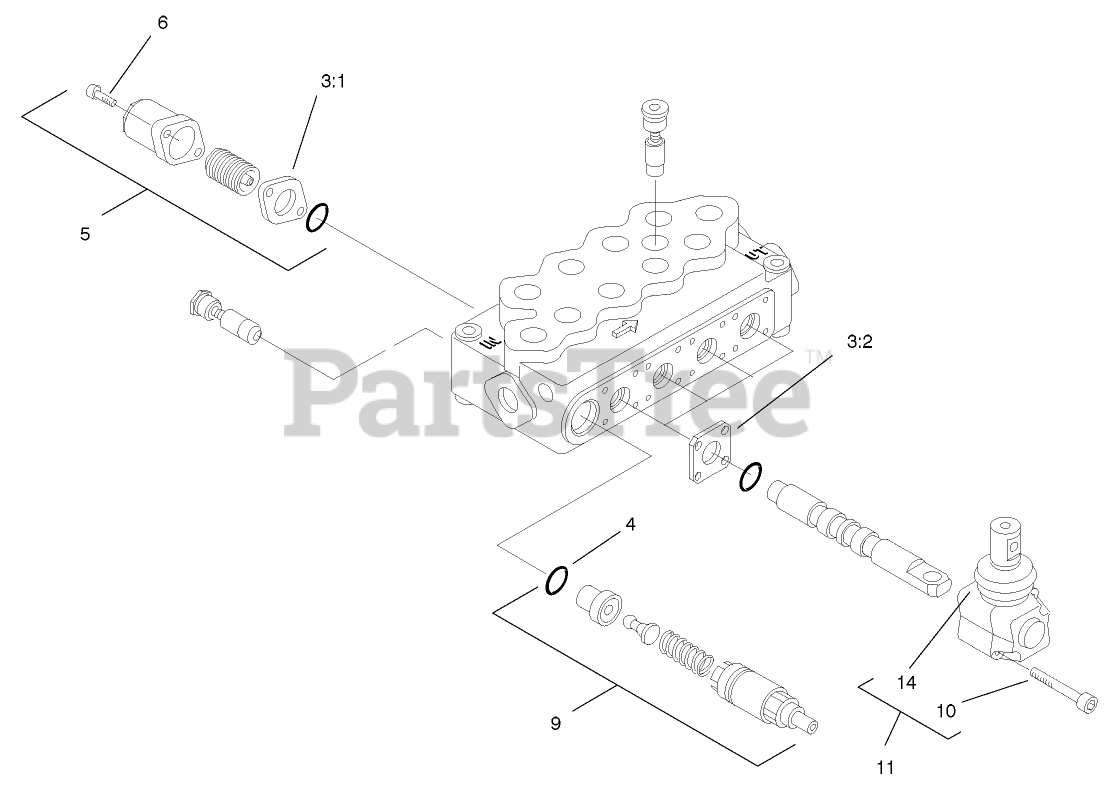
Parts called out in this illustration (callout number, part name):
3	SEAL KIT
3:1	GASKET
3:2	GASKET
5	STANDARD SPRING KIT
5	HIGH FORCE SPRING KIT
6	SCREW-CAP, END
9	VALVE-RELIEF
11	OPERATOR ASM
